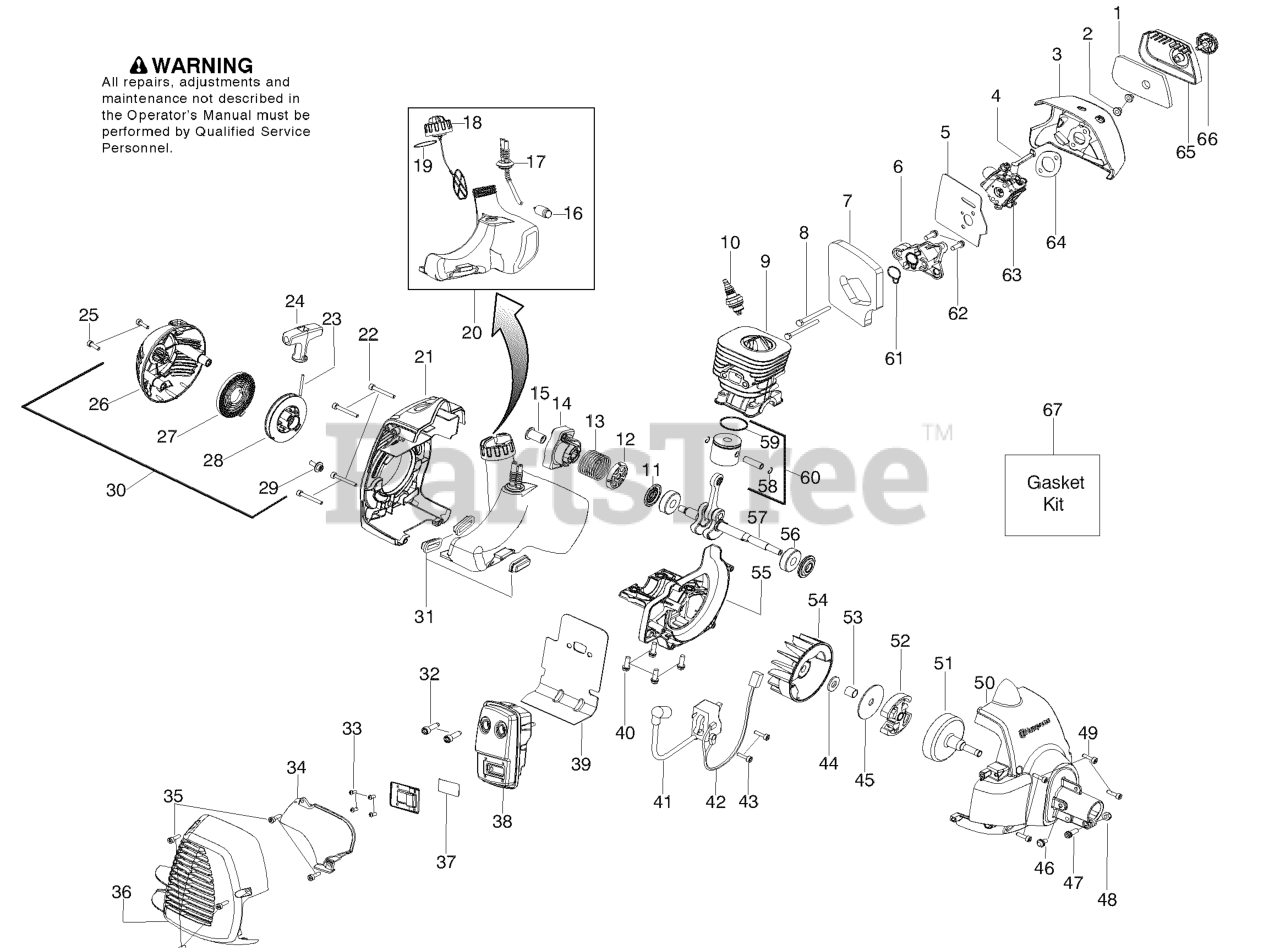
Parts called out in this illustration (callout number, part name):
1	FILTER AIRBOX
3	Air Box
4	CHOKE LEVER
5	KIT GASKET CARB
6	CARB ADAPTOR
7	KIT GASKET 28CC TRIMMER
8	BOLT CARB ADAPTOR
9	CYLINDER
10	Plug-Spark
11	KIT SEAL CRANKSHAFT
12	WASHER STARTER
13	SPRING STARTER CUP
14	ASSY-STARTER CUP
15	COUPLING STARTER
16	FUEL PICK-UP ASSY
17	KIT FUEL LINE
18	ASSY-CAP W/RETAINER
19	O RING NITRILE
20	FUEL TANK ASSY
21	REAR SHROUD
24	STARTER HANDLE GRAY
25	SCREW M5-0.8X30MM
26	STARTER HOUSING
27	%KIT STARTER SPRING
28	KIT STARTER PULLEY
30	ASSY-STARTER HSG.
31	ISOLATOR FUEL TANK
32	BOLT MUFFLER
33	SCREW-10-16 X 1/2 HI-LO
34	SHIELD HEAT
35	SCREW M4 X 1.75 PT 16MM
36	GUARD-MUFFLER
37	KIT SPARK ARRESTOR SCREEN
38	ASSY-MUFFLER
39	GASKET PAPER METAL
40	SCREW-M5-0.8 X 25MM(TAP)
41	IGNITION MODULE MBU-7
42	ASSY MODULE LEAD WIRE
43	SCREW M4 X .70 TT 16MM
44	WASHER CLUTCH
45	WASHER-CLUTCH
48	LOCKNUT-HEX 10-24
49	SCREW M4 X .70 TT 16MM
50	FAN HSG ASSY
51	Assy-Clutch Drum
52	%KIT CLUTCH ASSY
53	SPACER FLYWHEEL
55	CRANKCASE CASTING
56	BEARING RADIAL BALL (6201)
57	KIT CRANKSHAFT ASSY
58	WRIST PIN RET.
59	RING PISTON
60	KIT PISTON 28CC TRIMMER
61	KIT GASKET 28CC TRIMMER
62	SCREW-M5-0.8 X 25MM(TAP)
63	Kit-Carb.
64	KIT GASKET 28CC TRIMMER
65	COVER-AIR BOX
66	KNOB ASSY AIRBOX COVER
67	KIT GASKET 28CC TRIMMER
